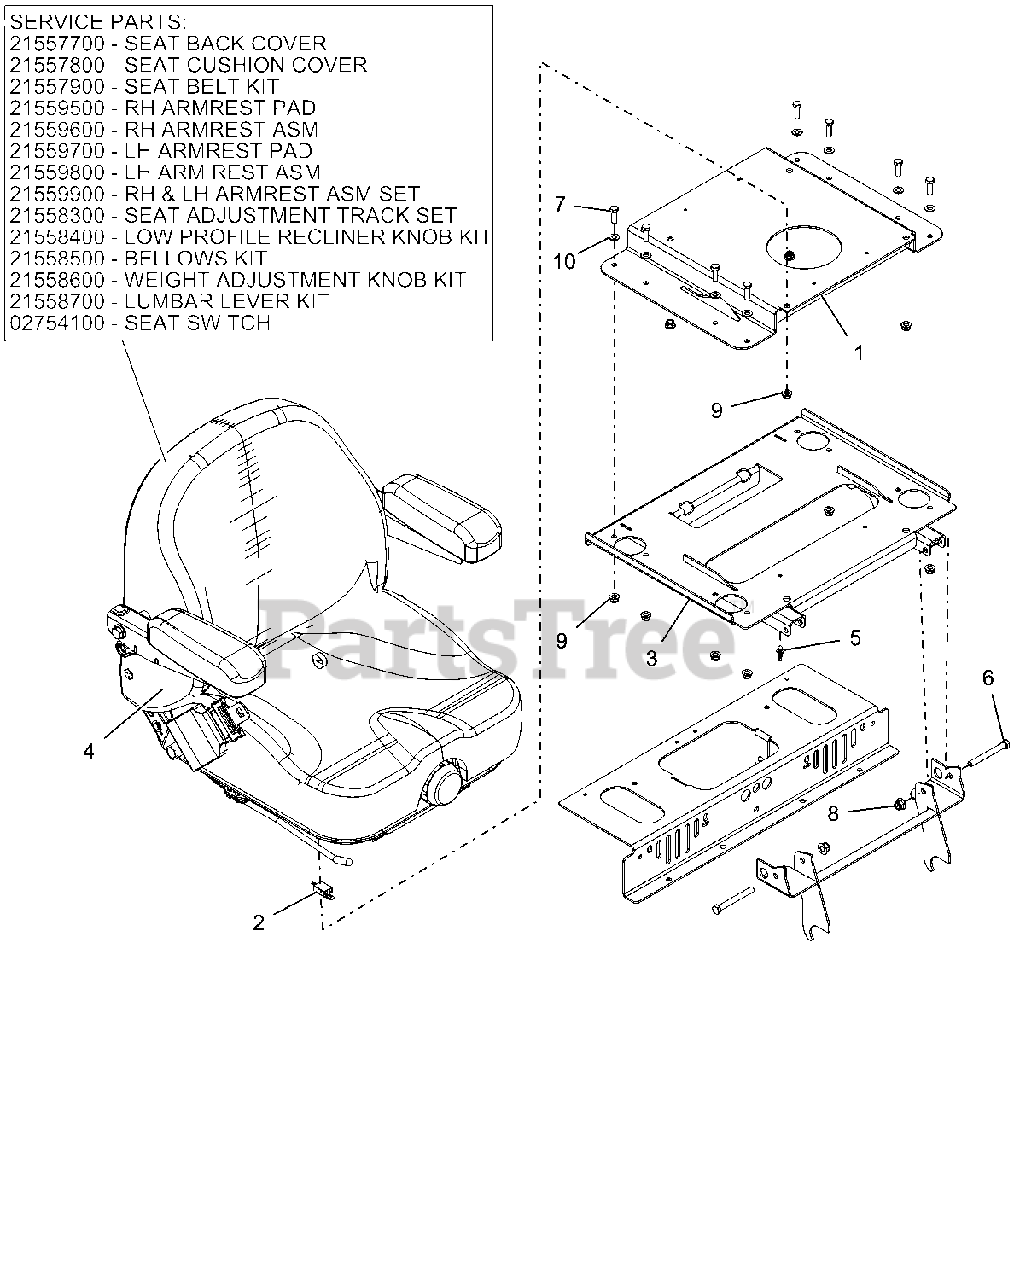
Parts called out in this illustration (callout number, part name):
1	SEAT BASE MOUNTING WLDM - RED
2	HARNESS, PT200 SEAT ADAPTER
3	SEAT ISO MOUNTING WLDMT - RED
4	SWITCH- SNAP MTG N.O.
4	SEAT, FULL SUSPENSION
4	COVER, SEAT BACK
4	COVER,SEAT CUSHION
4	KIT, SEAT BELT
4	SET, SEAT ADJUSTMENT TRACK
4	KIT, LOW PROFILE RECLINER KNOB
4	KIT, BELLOWS
4	KIT, WEIGHT ADJUSTMENT KNOB
4	KIT, LUMBAR LEVER
4	PAD, RH ARMREST
4	ASM, RH ARMREST
4	PAD, LH ARMREST
4	ASM LH ARMREST
4	SET, RH & LH ARMREST ASM
5	CABLE TIE W/ TREE (.25 HOLE)
6	@BLT-HEX .38-16X3.25 GR5 YWZC
7	@BLT-HEX .31-18X1.00 GR5 YWZC
8	@NUT-LK-NYL-FLG .38-16 YWZC
9	@NUT-LK-NYL-FLG .31-18 YWZC
10	@WSHR-FL-STL.344X.688X.065YWZC
